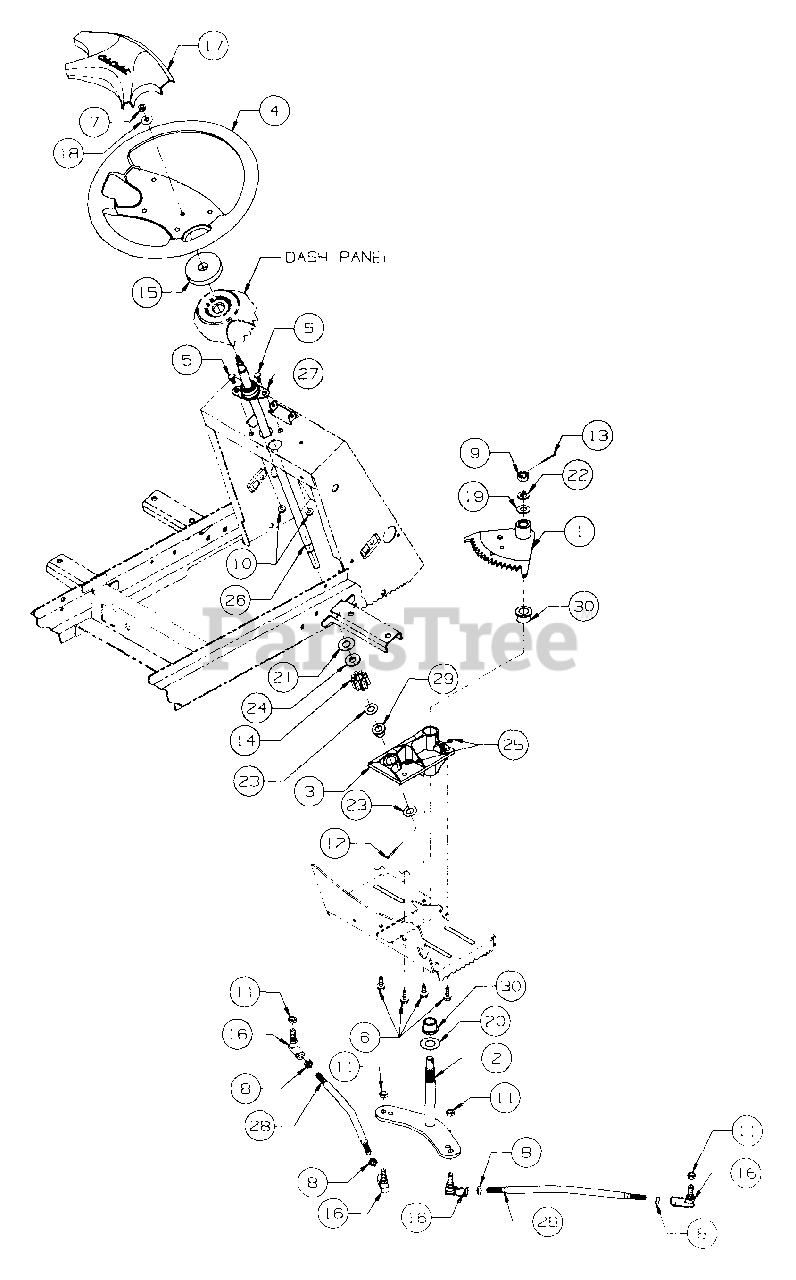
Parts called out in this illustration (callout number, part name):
1	Segment Assy, 1ST Steering
2	Arm Assy, Lower Steering
3	Housing Assy,
4	Wheel, Steering
5	Screw, Hex Cap, 1/4 - 20 x .62, GR5
6	Screw, Hx Wsh Hd-TPTT, 5/16-18 x .75
7	Nut, Hex Center Lock, 5/16-24
8	Nut, Hex Jam, 3/8-24 GR5
9	Nut, Hex Slotted, 1/2-20 GR5
10	Nut, Hex Flange Lock, 1/4-20
11	Nut, Hex Lock, 3/8-24 GR5
12	Pin, Cotter, 1/8 Dia x 1
13	Pin, Cotter, 3/32 Dia x 1.25
14	Pinion, Steering
15	Gasket, Steering
16	Joint, Ball, 3/8-24
17	Insert, Steering Wheel
18	Washer, Bell, .340 x .88 x .06 Thk
19	Washer, Flat, .510 x 1 x .06 Thk
20	Washer, Flat, .760 x 1.5 x .03 Thk
21	Washer, Flat, .56 x 1 x .04 Thk
22	Washer, Lock, 1/2
23	Washer, Flat, .531 x 1 x .027 Thk
24	Wshr, Rubber Flat, .50 x 1.12 x .125 Thk
25	Fitting, Grease, 3/16 Drive Type
26	Shaft, Steering
27	Bearing, Flange
29	Bearing, Flange, .503 ID
30	Bearing, Bronze Flange, .75 ID
